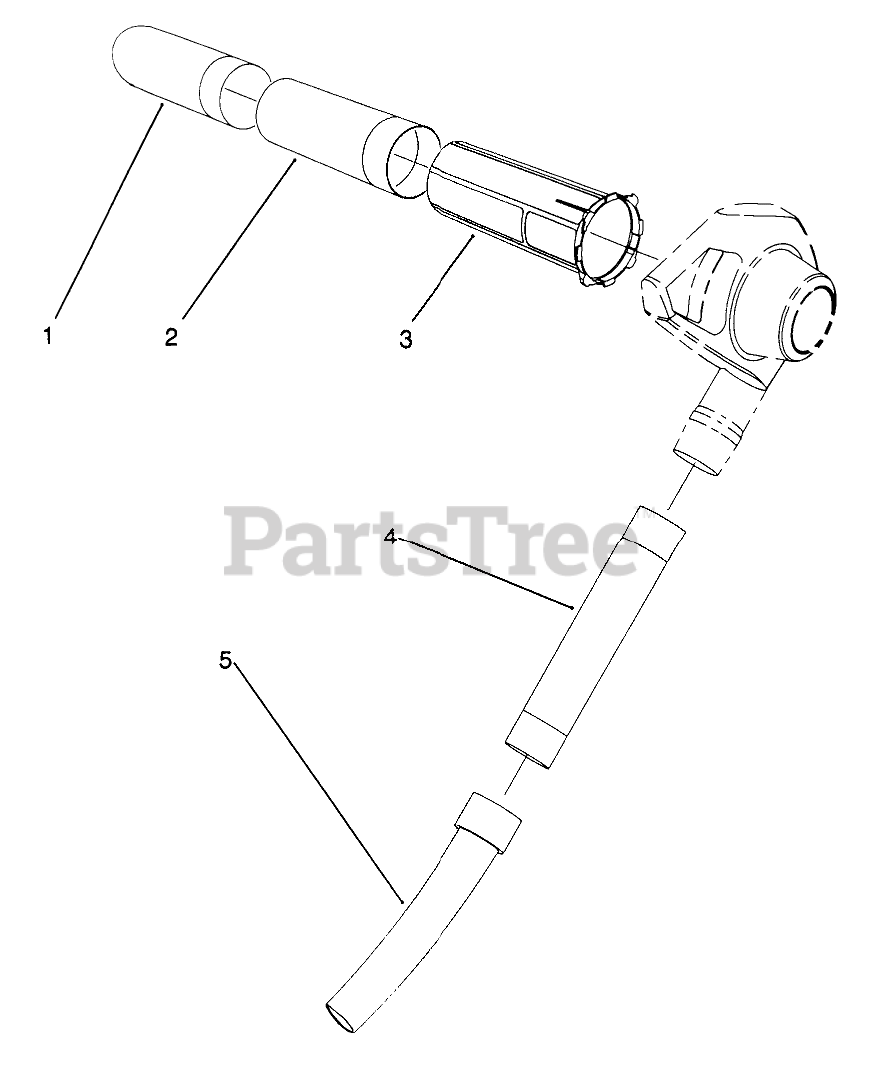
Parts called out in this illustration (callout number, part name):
1	LOWER VAC TUBE
2	MIDDLE VAC TUBE
3	UPPER VAC TUBE
4	BLOWER TUBE
5	MID BL-DISCHARGE TUBE
